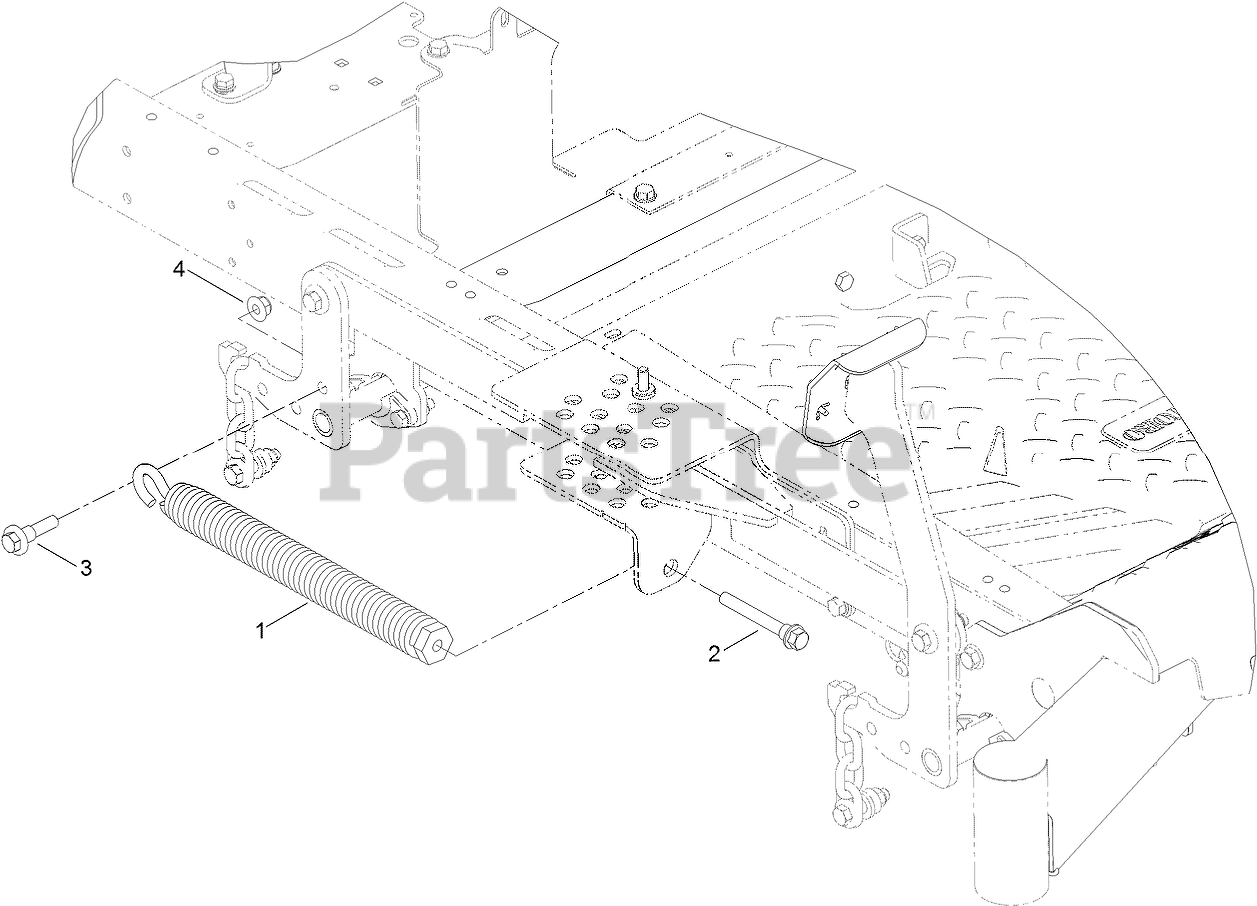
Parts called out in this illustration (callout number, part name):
1	SPRING-EXTENSION
2	BOLT-SHOULDER
3	BOLT-SHOULDER
4	NUT-HF, NI
